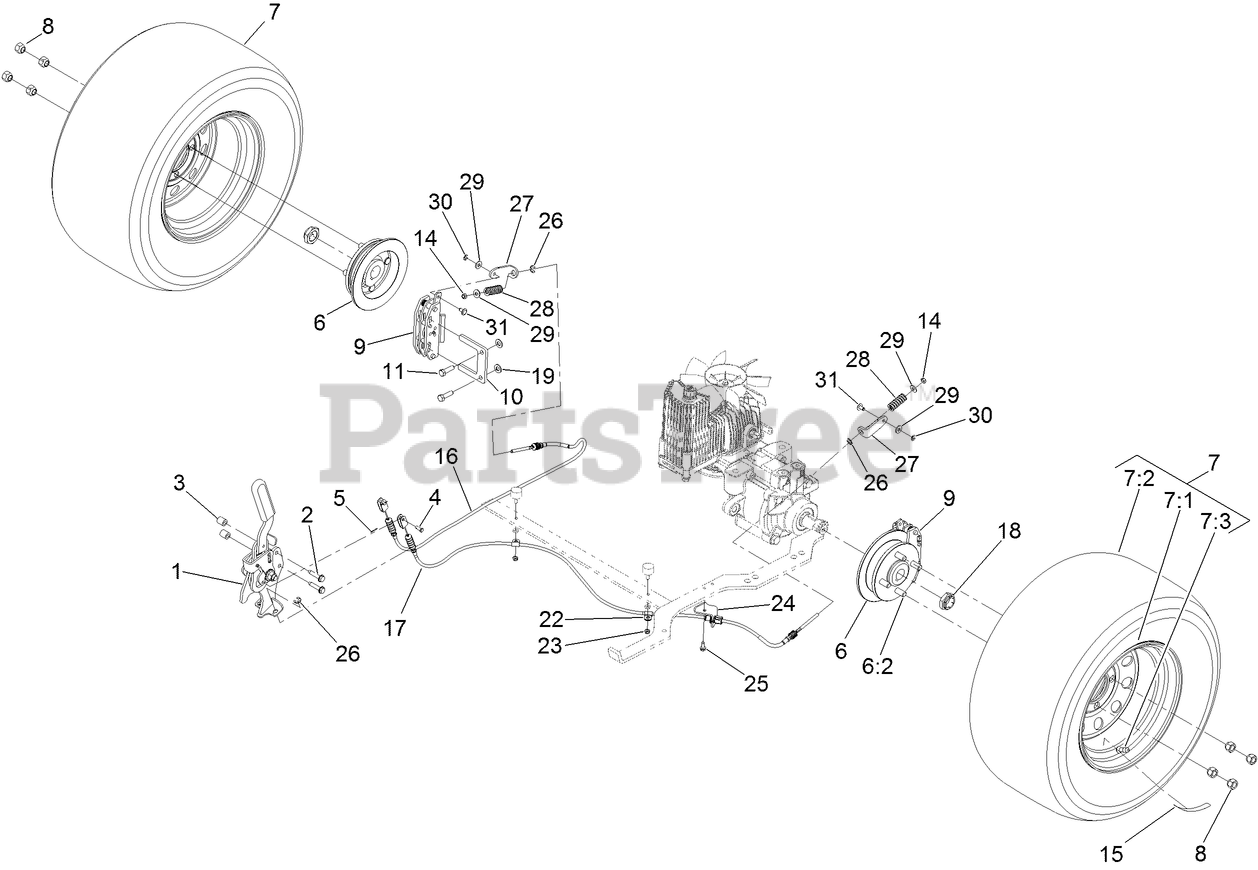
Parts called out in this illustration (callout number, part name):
1	BRAKE HANDLE ASM
3	SPACER
4	PIN-CLEVIS
5	PIN-COTTER
6	WHEEL HUB ASM
6:2	STUD-WHEEL
7	WHEEL AND TIRE ASM
7:1	RIM ASM
7:2	TIRE
7:3	STEM-VALVE
8	NUT-LUG
9	CALIPER-BRAKE
10	PLATE-MOUNT, BRAKE
11	SCREW-LOCK, PATCH
14	NUT-LOCK, NI
15	DECAL-WHEEL NUT TORQUE
16	CABLE-PARK BRAKE, RH
17	CABLE-PARK BRAKE, LH
18	LOCKNUT
19	WASHER-FLAT
23	NUT-LOCK, NI
24	BRACKET-CABLE
25	SCREW-HWH
26	E-RING
27	BRACKET-BRAKE, L
28	SPRING-DIE
29	WASHER-FLAT
30	E-RING
31	PIN-BRAKE
